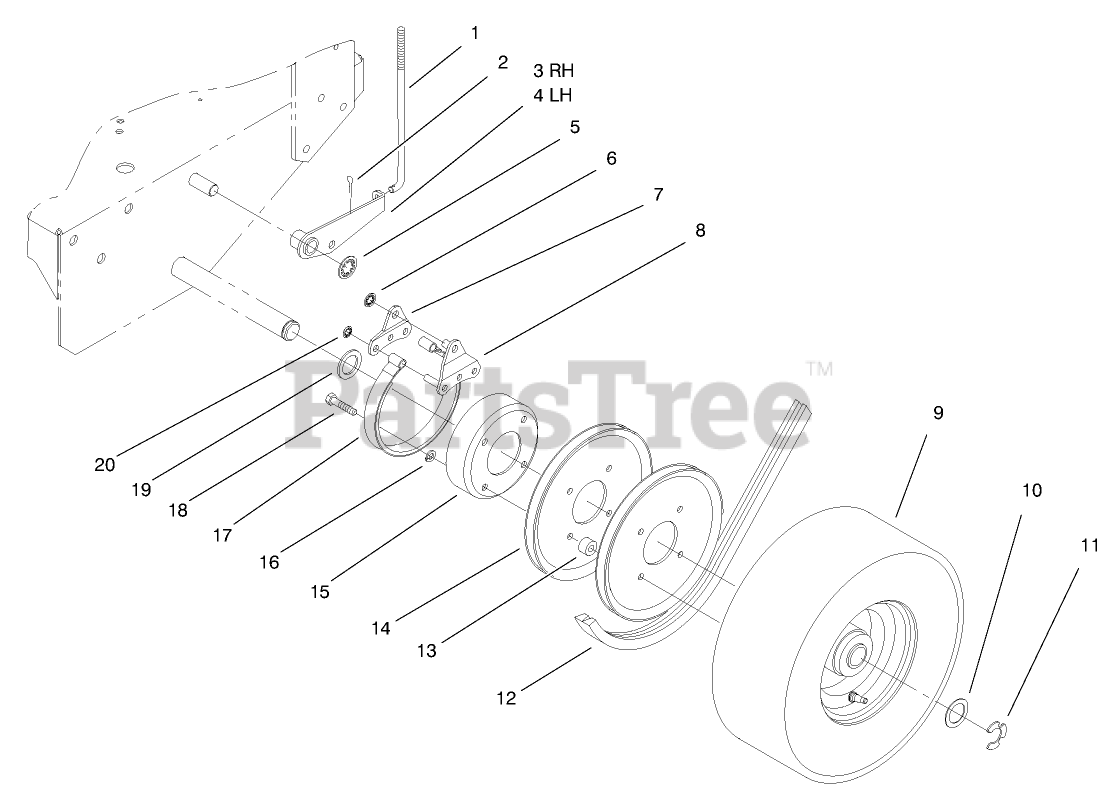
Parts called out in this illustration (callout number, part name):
1	ROD-BRAKE
2	PIN-COTTER
3	Arm-Brake RH
4	Arm-Brake LH
5	RING-RETAINING
6	RING-RETAINING, EXTERNAL
7	Plate-Link
8	LINK-Brake
9	WHEEL ASM
10	WASHER-THRUST
11	RING-RETAINING
12	V-BELT
13	SPACER-PULLEY
14	Pulley-Wheel
15	Drum-Brake
16	WASHER-LOCK
17	BAND-BRAKE
18	SCREW-HH
19	WASHER-WHEEL
20	RING-RETAINING
